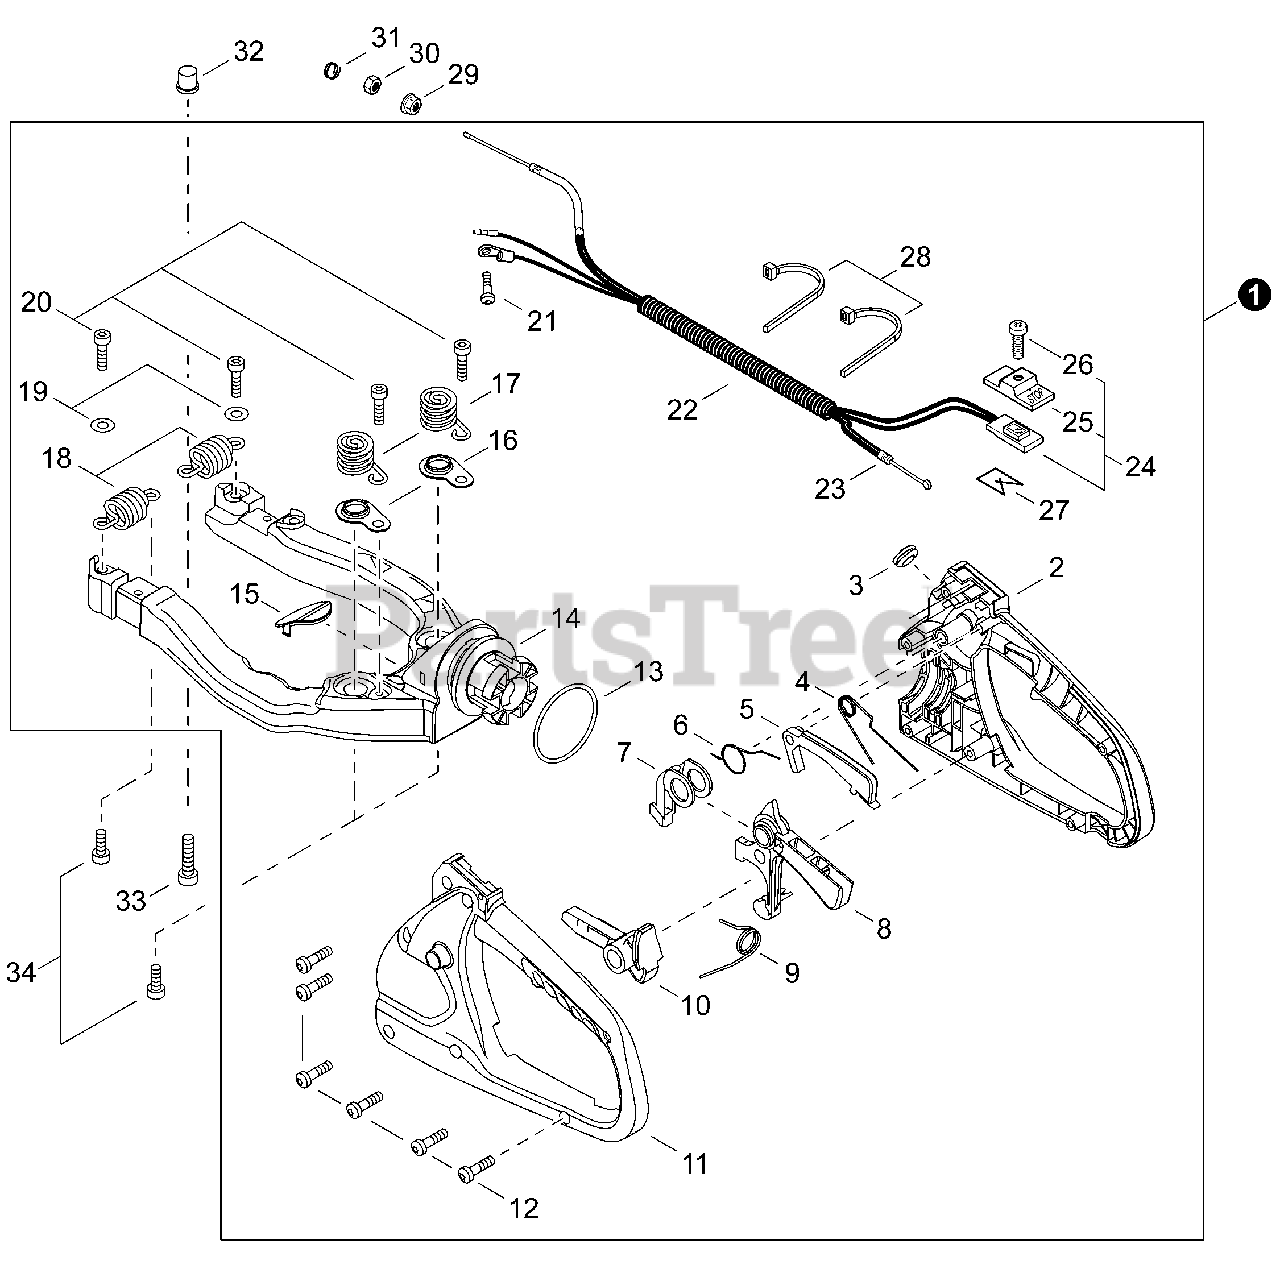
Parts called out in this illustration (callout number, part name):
1	HANDLE ASSY, REAR
2	HANDLE, RIGHT REAR
3	GROMMET
4	SPRING, TORSION
5	LOCKOUT, THROTTLE
6	SPRING, COIL
7	LEVER, THROTTLE
8	TRIGGER, THROTTLE
9	SPRING, TORSION
10	LEVER, HANDLE RELEASE
11	HANDLE, LEFT REAR
12	BOLT, TORX 4×16
14	FRAME
15	COVER, HANDLE
16	HOLDER, SPRING
17	SPRING, COMPRESSION
18	SPRING, COMPRESSION
20	BOLT, TORX 6×20
21	BOLT, TORX 4×8
22	TUBE, PROTECTIVE
23	CABLE, THROTTLE
24	SWITCH, ON-OFF
25	KNOB, SWITCH - RED
26	SCREW 3×10
28	STRAP, TIE
29	NUT, FLANGE 6
33	BOLT, TORX 6×25
34	BOLT, TORX 6
